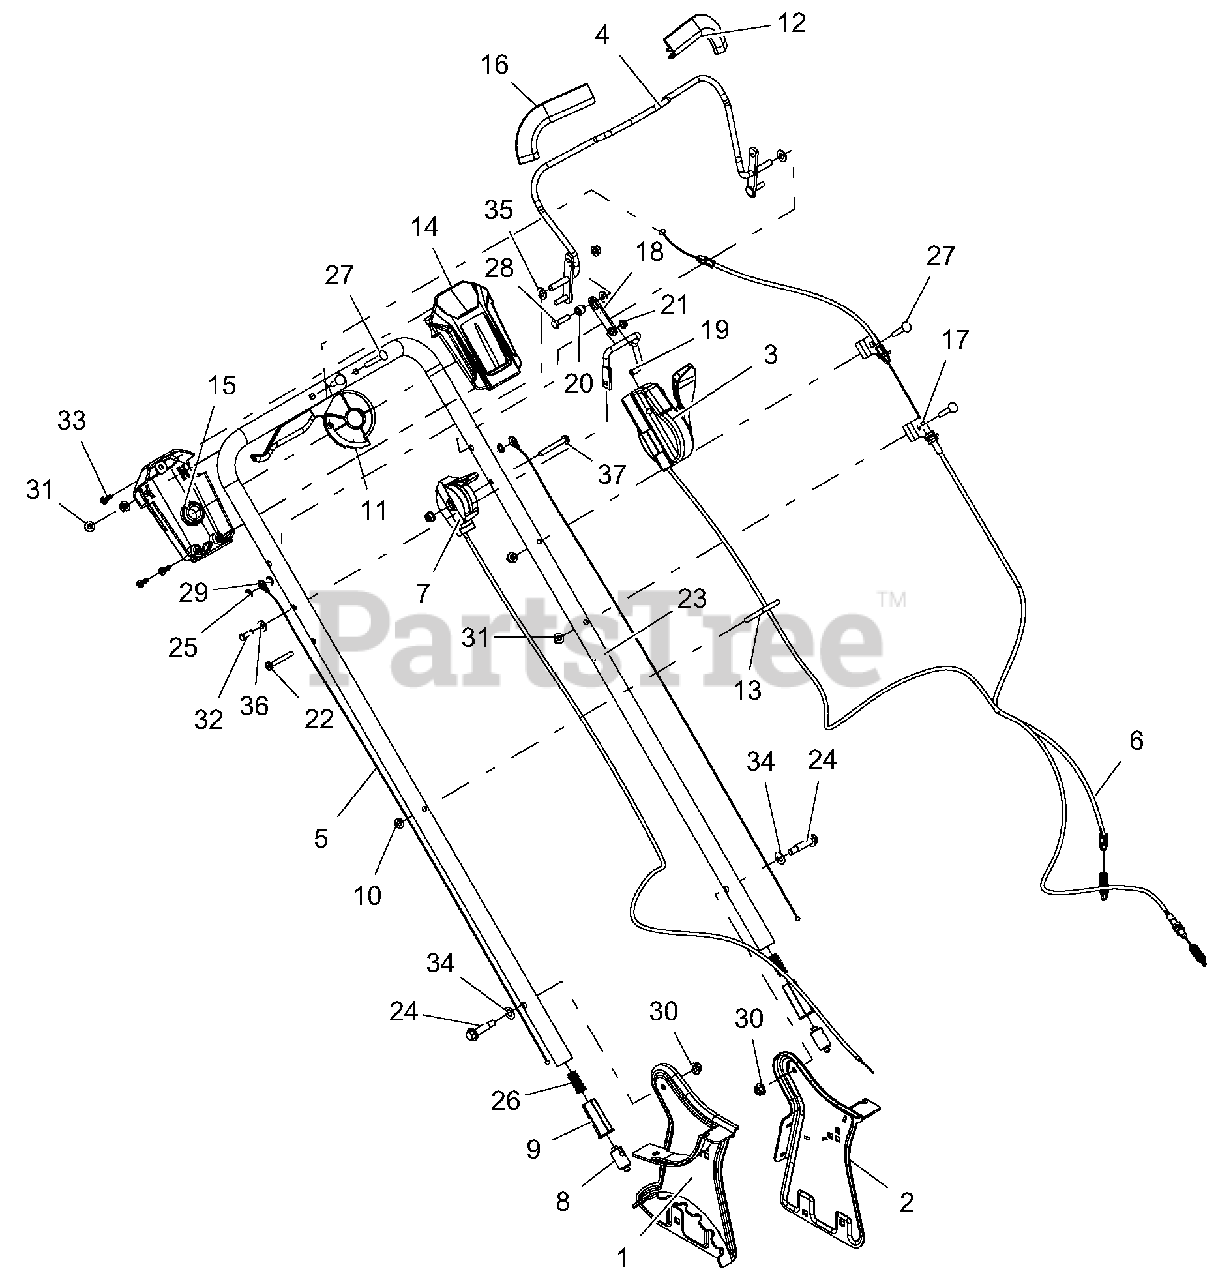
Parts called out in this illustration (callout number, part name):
1	SUPPORT, RH HANDLEBAR
2	SUPPORT, LH HANDLEBAR
3	ASSY, BBC CONTROL
4	WLDMT, OPC BAIL, BBC
5	CABLE, LM HANDLE ADJUST
6	CABLE, DRIVE CONTROL
7	CONTROL, THROTTLE
8	PLUNGER, HANDLEBAR LOCKING
9	INSERT, HANDLEBAR ADJUST
10	@NUT-LK-NYL-FLG .25-20 YWZC
11	HANDLE, DRIVE CONTROL
12	GUARD, FINGER - LH
13	HOLDER, RECOIL CORD
14	HOUSING, UPPER DRIVE CONTROL
15	HOUSING, LOWER DRIVE CONTROL
16	GUARD, FINGER - RH
17	BRKT, CABLE - DRIVE
18	COUPLER, BBC CONTROL
19	WIREFORM, BBC CONTROL
20	BSHG, BBC LATCH
21	BUSHING, NYLON, .31, SPLIT
22	SCR M6-1.0X45 DIN7985A PH YWZC
23	HANDLEBAR, LM
24	BLT-SHLDR, .50X1.15X.312-18GR5
25	NUT-PUSH .25X.50 O.D.
26	SPRING, COMPRESSION
27	@BLT-RDHDSQNK .25-20X1.50 G5YZ
28	@BLT-HEX .25-20X1.00 GR5 YWZC
29	RG-RTNG-EXT .250X.010
30	@NUT-LK-TOP-FLG .31-18 YWZC
31	@NUT-LK-TOP-FLG .25-20 YWZC
32	PIN, .25 X .75
33	SCR-TAP 12-14X.75PLSTITE @BLZC
34	WSHR,.385X.745X.030 STL YWZC
35	@WSHR-FL-STL.344X.688X.065YWZC
36	@WSHR-FL-STL.281X.62X.065 YWZC
37	SCR, .25-20X2.00 PH PAN YWZC
